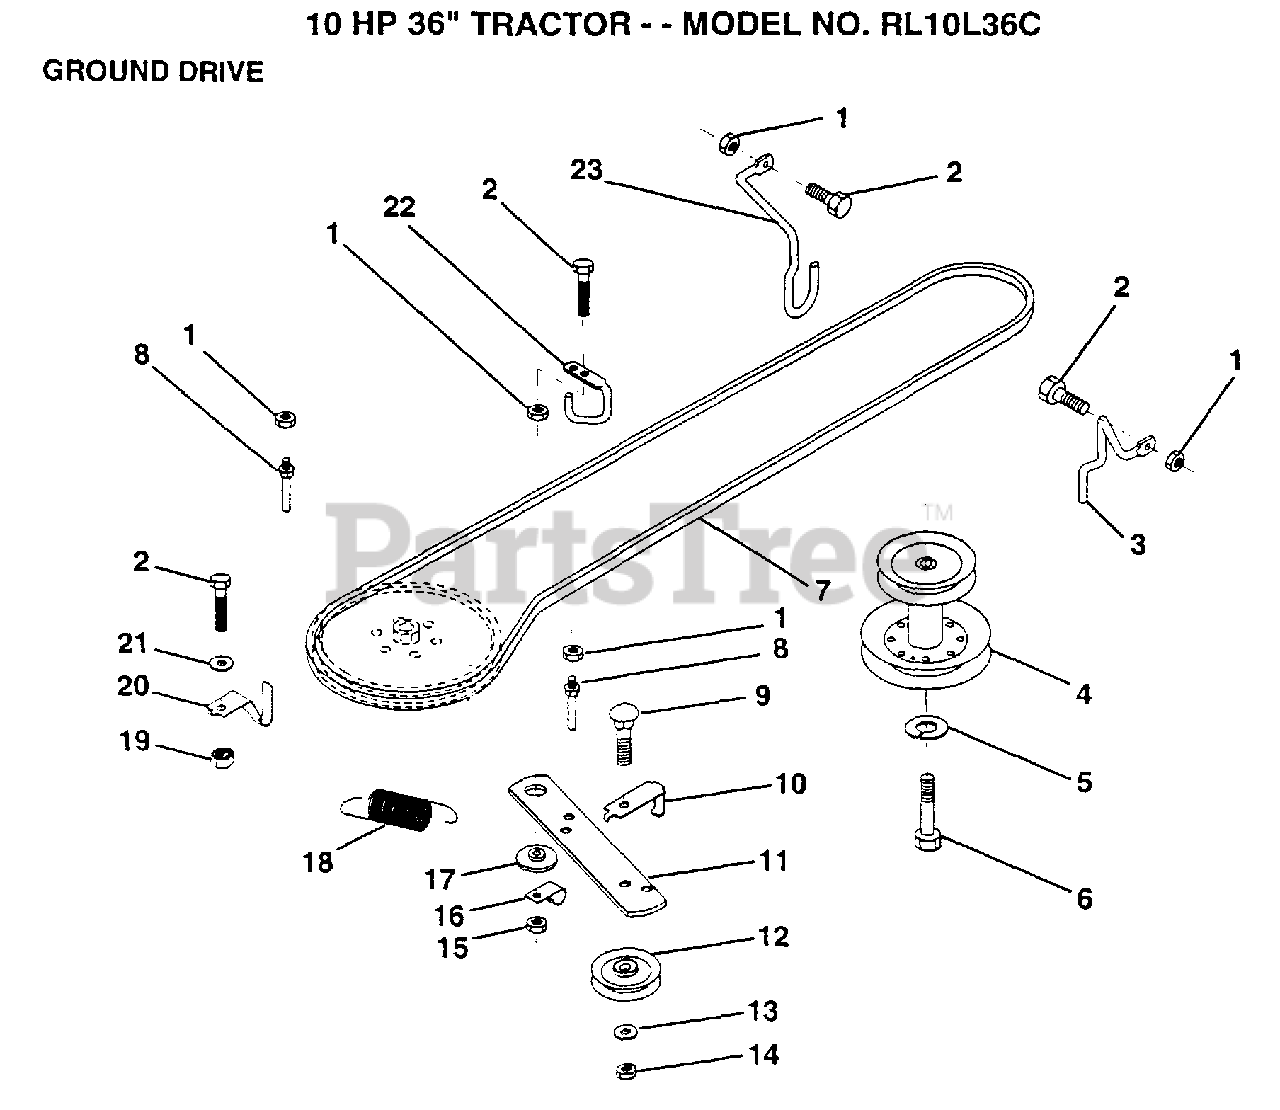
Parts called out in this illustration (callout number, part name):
1	NUT
2	BOLT
3	KEEPER RH
4	PULLEY.ENGINE.LR
5	LOCKWASHER
6	HEX BOLT
7	BELT
8	"KEEPER,DRIVE BELT"
9	BOLT
10	"KEEP,IDLER DR BEL"
11	ARM IDLER CLUT GD
12	PULLEY.IDLER.FLAT
13	WASHER
14	LOCKNUT
15	NUT
16	"CLIP,INSULATOR"
17	SPACER RETAINER
20	KEEPER.BELT.T/A
21	WASHER
22	"KEEPER,FRA DR BEL"
23	KEEPER MOWER LH
